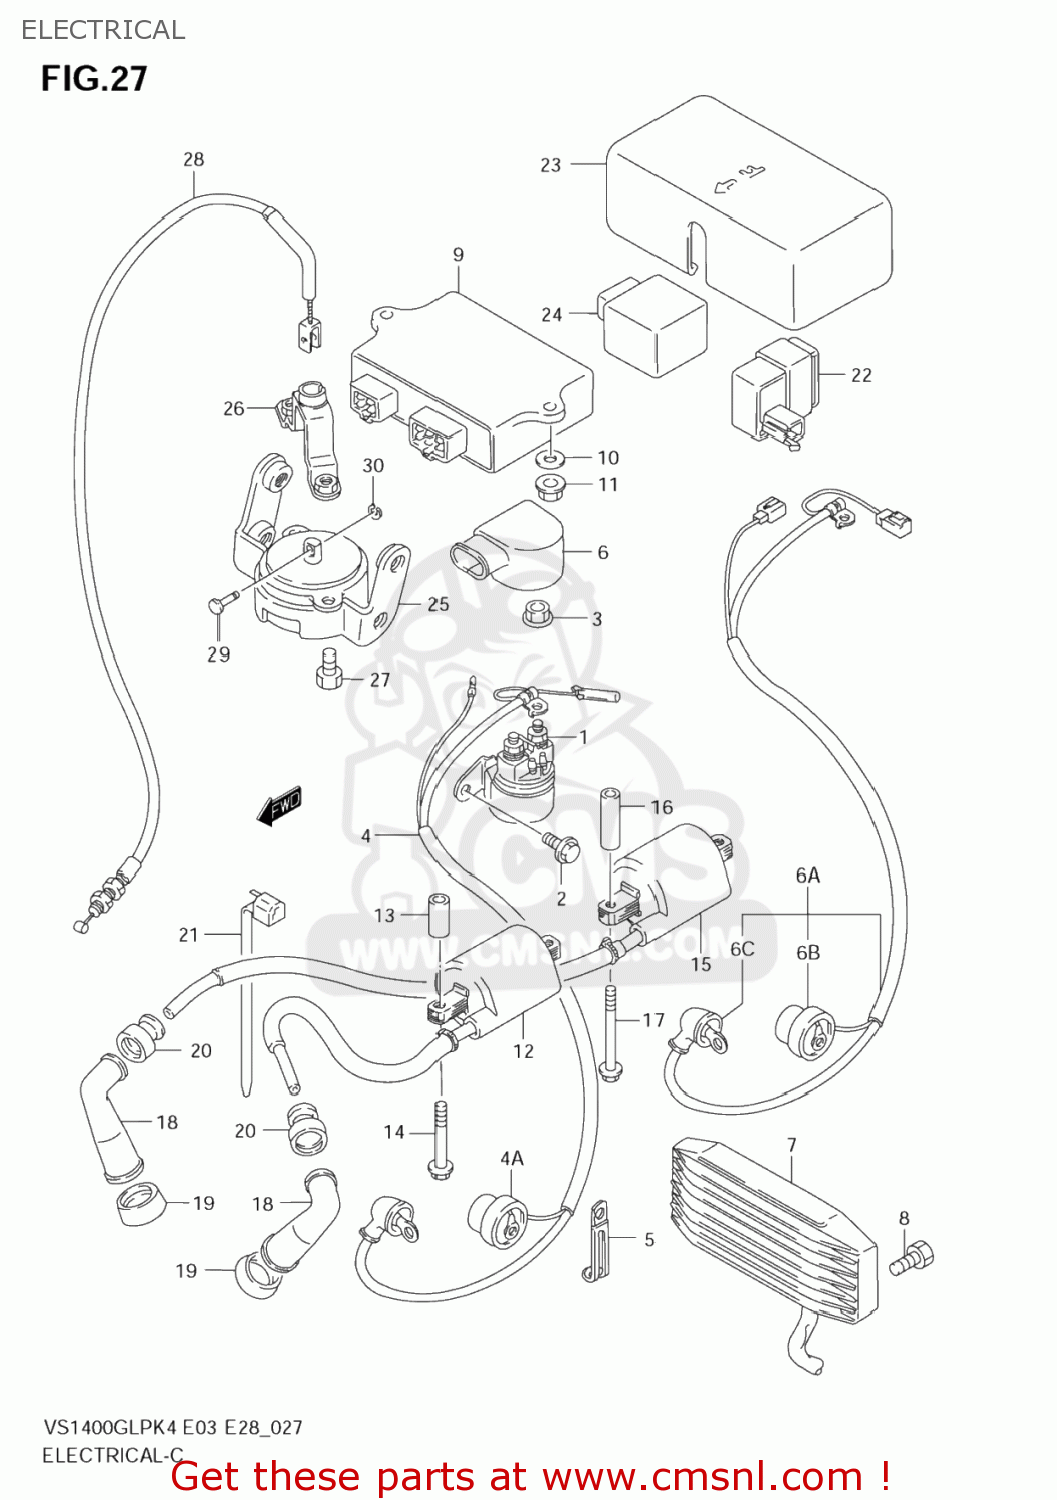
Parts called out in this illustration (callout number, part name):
1	RELAY ASSY,STARTING MOTOR
2	BOLT
3	NUT
4	WIRE,STARTER MOTOR LEAD
4A	CAP,OIL PRESSURE SWITCH
5	CLAMP L:35
6	CAP,STARTER RELAY TERMINAL
6A	WIRE,STARTER MOTOR LEAD
6B	CAP,OIL PRESSURE SWITCH
6C	CAP,STARTER MOTOR LEAD
7	RECTIFIER ASSY
8	BOLT
9	IGNITOR ASSY
10	WASHER(6.5X16X4)
11	NUT
12	COIL ASSY,IGNITION RR
13	SPACER(6.4X10X22)
14	BOLT
15	COIL ASSY,IGNITION
16	SPACER(6.4X10X32)
17	BOLT
18	CAP,SPARK PLUG
19	SEAL,SPARK PLUG
20	SEAL,HIGH TENSION CORD
21	CLAMP(L:125)
22	RELAY ASSY,FUEL CUT
23	COVER,RELAY
24	CONTROL UNIT,DECOMP
25	SOLENOID ASSY,DECOMP
26	BRACKET,DECOMP SOLENOID
27	BOLT
28	CABLE ASSY,DECOMP FR
29	PIN(4X12.5)
30	E RING
